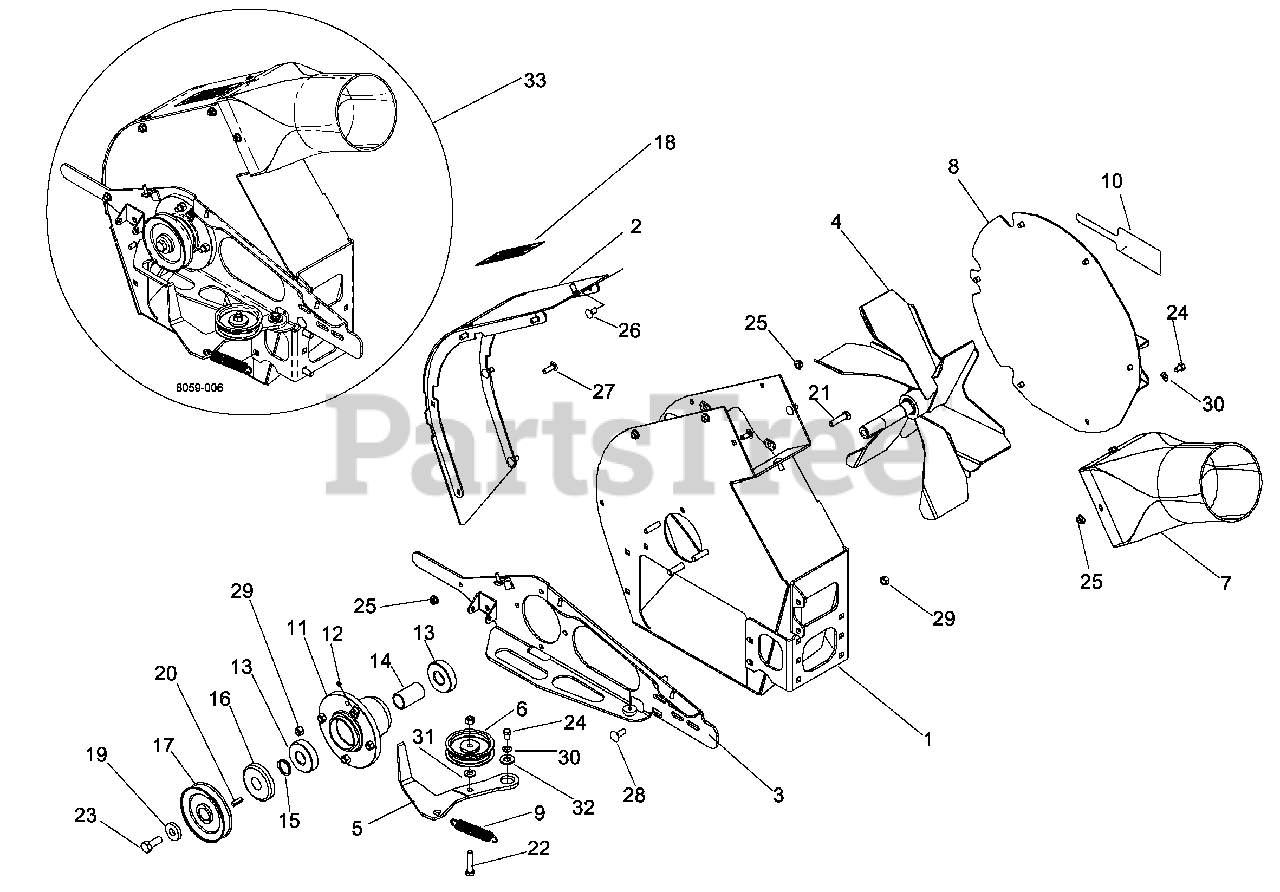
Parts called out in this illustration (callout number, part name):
1	HOUSING WLDT
2	SANDLINER W/DECAL
3	HUB PLATE
4	FAN WLDT.
5	IDLER ARM
6	PULLEY, IDLER 3 METAL
7	BLOWER EXIT TUBE
8	OUTER PLT WLDT
10	DECAL, DIXON
11	DECK HUB MACHINED
12	ZERK, 3/16, DRIVE IN
13	BEARING - 6305 - 2RS
15	HUB PULLEY SPACER
16	TRASH GUARD
18	G.C.WARNING DECAL
19	WASHER .525 X 1.375 X .25
20	KEY - 1/4 X .88
21	HCS 3/8C X 1 1/2
22	HCS 3/8-16 X 1 3/4 GR5
23	1/2-20 UNF X 1 1/4 HHBLT
24	5/16-18X1/2 HHB GR5
25	5/16-18 FLANGED L-NUT
26	BOLT 5/16C X 3/4" CARRIAGE
27	RHSSNB 5/16C X 1.0
28	RHSNB 3/8C X 1
29	NUT 3/8-16 NYLOC
30	FLAT WASHER 5/16 SAE
31	WASHER 3/8 SAE FLAT
32	WASHER 1/2" FLAT
